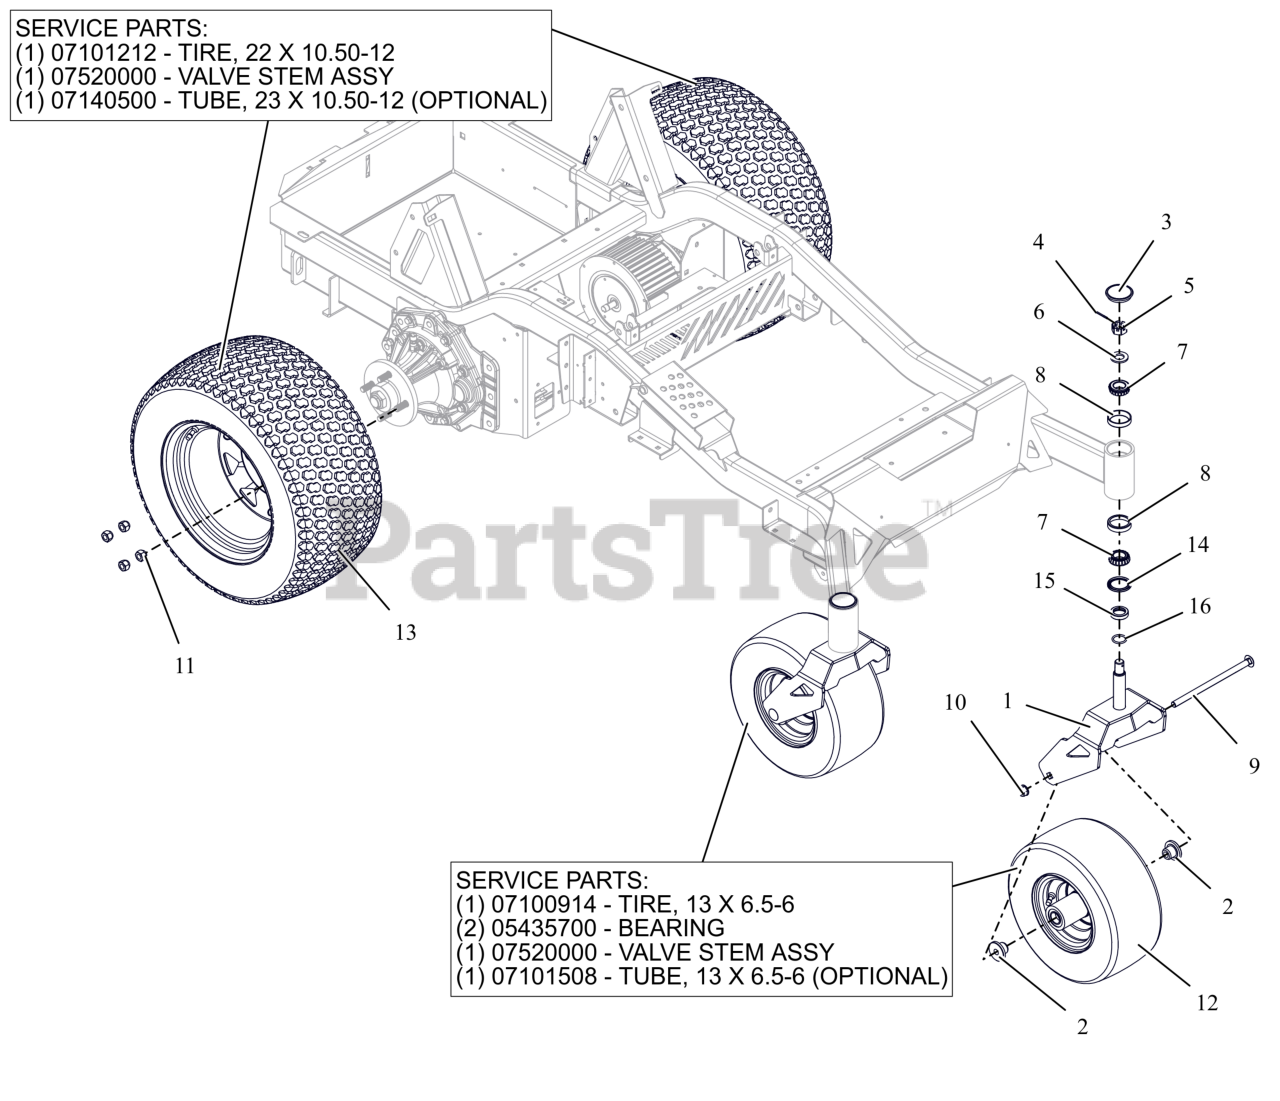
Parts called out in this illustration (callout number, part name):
1	WLDMT- CASTER FORK
2	SPACER, FRONT WHEEL
3	CAP, DUST
4	PIN,CTR.12X1.25EXTPRSQCT ZC120
5	NUT, SLOTTED .75-16
6	WSHR-FL-STL 0.812X1.469X0.134 ZCC
7	BRG-CONE 1.0X.58
8	BRG-CUP1.980X.420
9	BLT-RHSN .50-13X9.00 G5 ZCC NS
10	NUT-LK-CTR-FLG .500-13 GG ZCC
11	NUT, WHEEL .50-20 ZCC
12	ASM-TIRE/WHEEL 13X6.50-6
12	TIRE, 13X6.50-6 SMOOTH
12	BRG, 25MM ID X 52MM OD X 15MM
12	VALVE STEM ASS'Y
12	TIRE TUBE 13X6.5-6
13	ASM, WHL/TIRE 22X10.5-12 LG BLK
13	TIRE, 22X10.50-12
13	VALVE STEM ASS'Y
13	TUBE 22,23&24X8.50/9.50/10.00/10.50/12.00-12
14	BEARING SEAL 1.5 X 2 X .18
15	SPCR, CASTER FORK (1.00)
16	O-RING 1.000X1.250X
